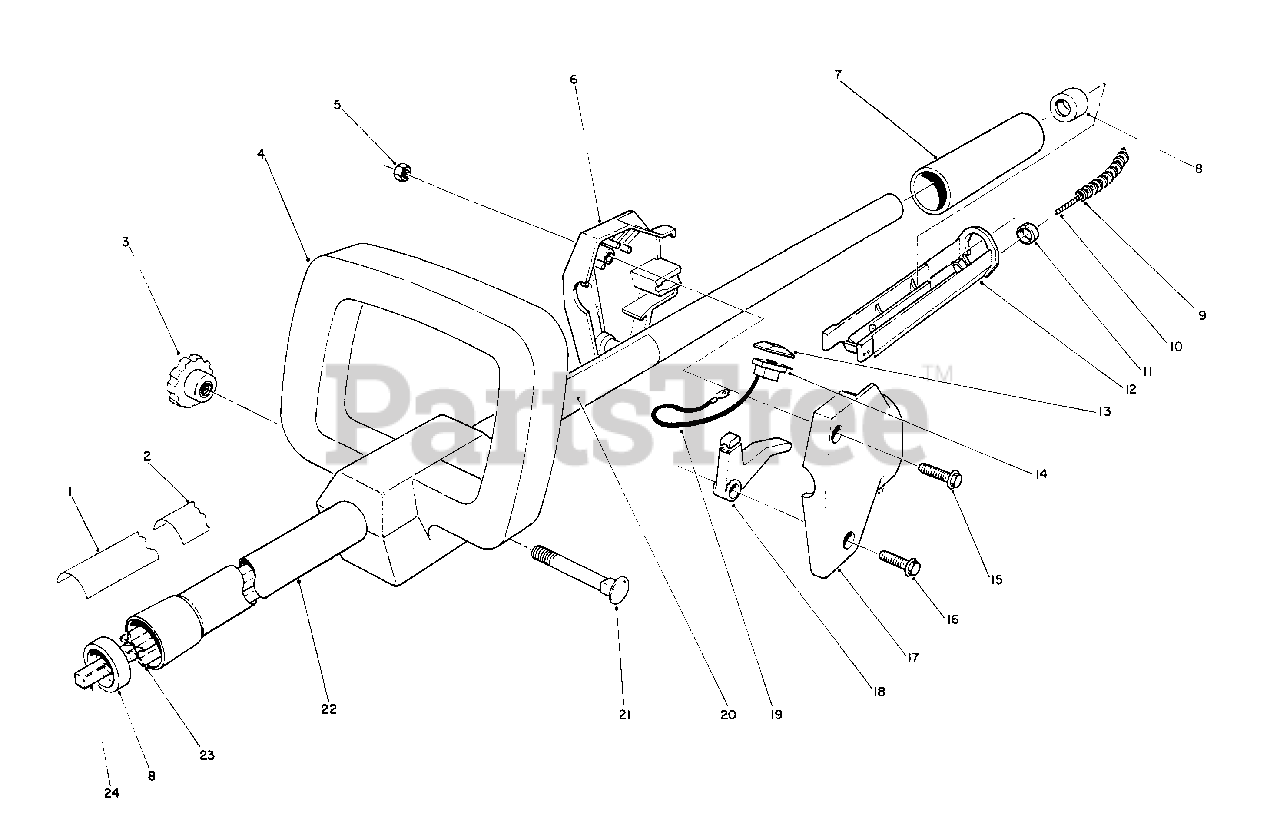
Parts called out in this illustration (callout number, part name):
1	Decal-TC 3105
2	Decal-Danger
4	Handle-Secondary
5	Nut-Lock
7	Grip-Drive Housing
8	Retainer-Casing
9	Cover-Cable
10	Cable-Throttle
12	Trough
13	Cap-Switch
15	Screw-Hex. Hd.
16	Screw-Hex. Hd.
17	Housing L.H.
18	Lever-Throttle
20	Decal-Instruction
21	Bolt-Carriage
23	Spacer-Shaft
24	Shaft-Drive, Wound
